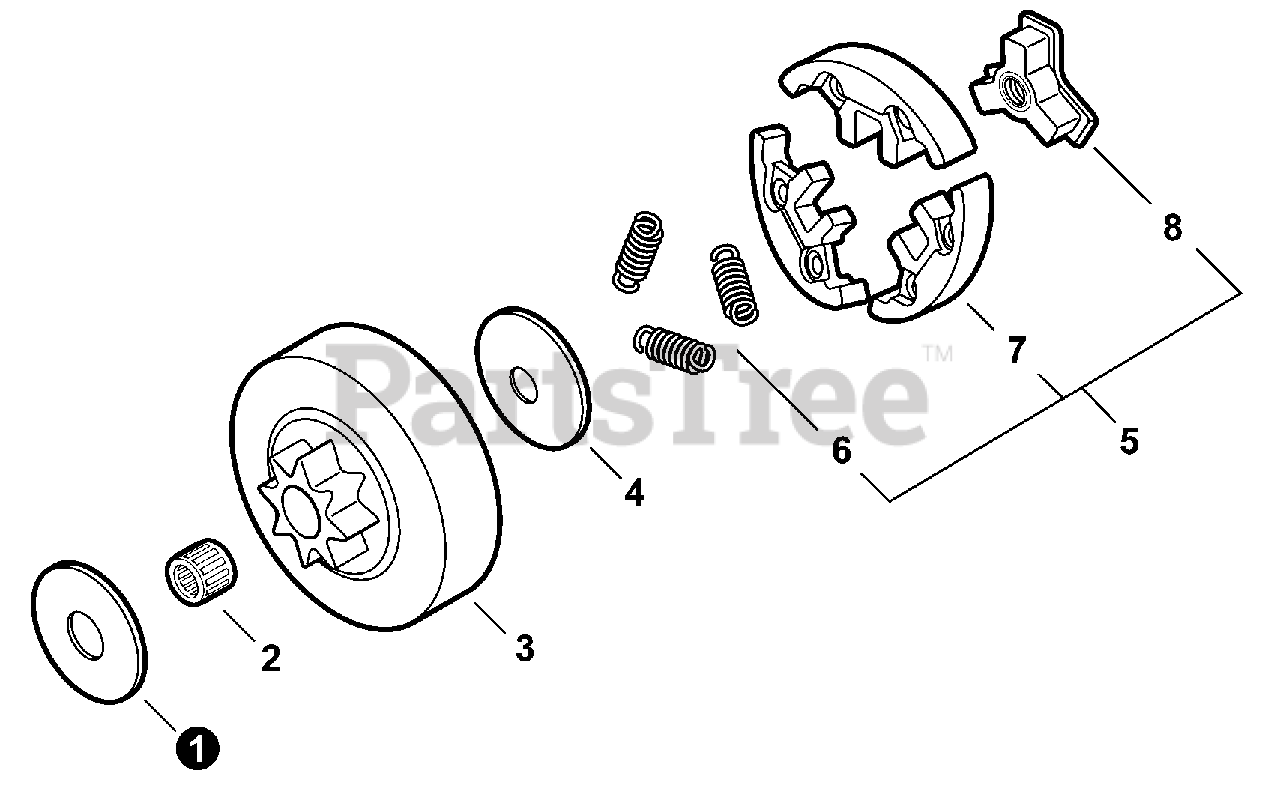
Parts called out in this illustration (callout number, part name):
1	WASHER 10.2×24.5×1.2
2	BEARING, NEEDLE 10
3	DRUM, CLUTCH
4	PLATE, CLUTCH
5	CLUTCH ASSY
6	SPRING, TENSION
7	SHOE SET, CLUTCH (3PCS)
8	HUB, CLUTCH
